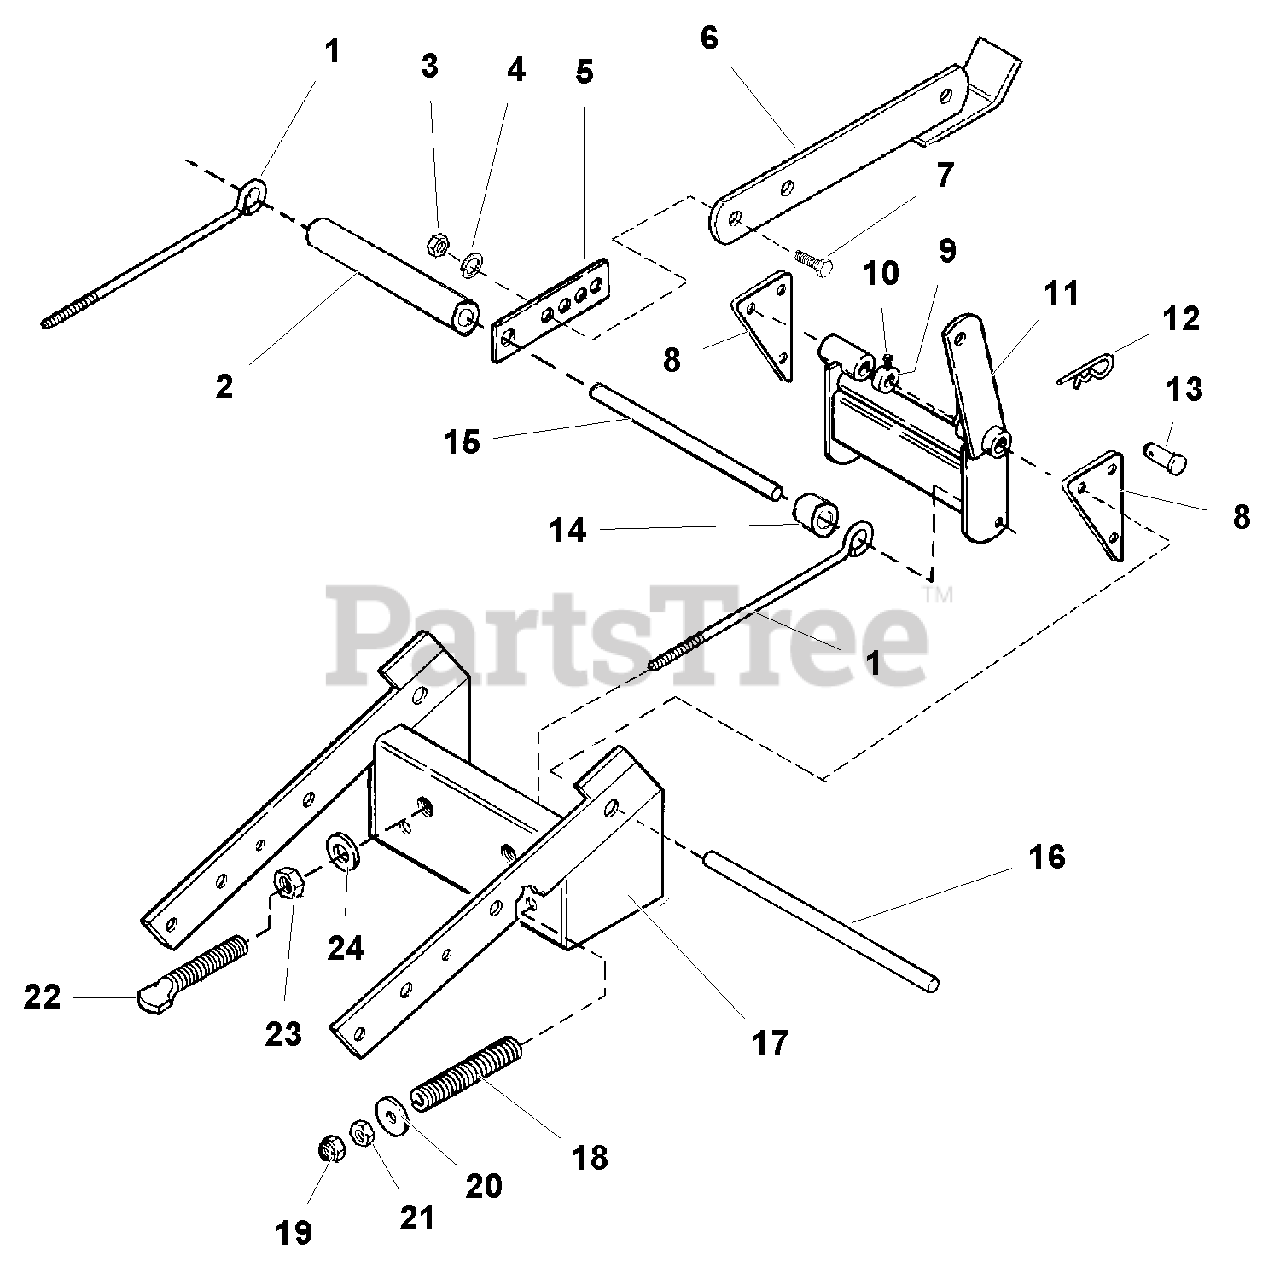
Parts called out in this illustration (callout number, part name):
1	EYEBOLT, 3/8-16
3	NUT, Hex, 1/2-13
4	LOCKWASHER, 1/2
5	BAR, Lift, Front
6	LIFT BAR ASSEMBLY
7	CAPSCREW, Hex Head, 1/2-13 x 1-3/4
8	ANCHOR, Front
9	SET COLLAR
10	SETSCREW, Square Head, Cup Point, 5/16-18 x 1/2, G8
11	PIVOT ASSEMBLY, Hitch
12	CLIP, Safety
13	PIN, Clevis, 5/8 x 2-1/4
16	SHAFT, Inner
17	HITCH ASSEMBLY
18	SPRING, Compression
19	NUT, Hex Jam, 3/8-16
20	WASHER, 3/8
21	NUT, Hex, 3/8-16
22	STUD, 3/4-10
23	NUT, Hex, 3/4-10
24	WASHER, Lock, 3/4
